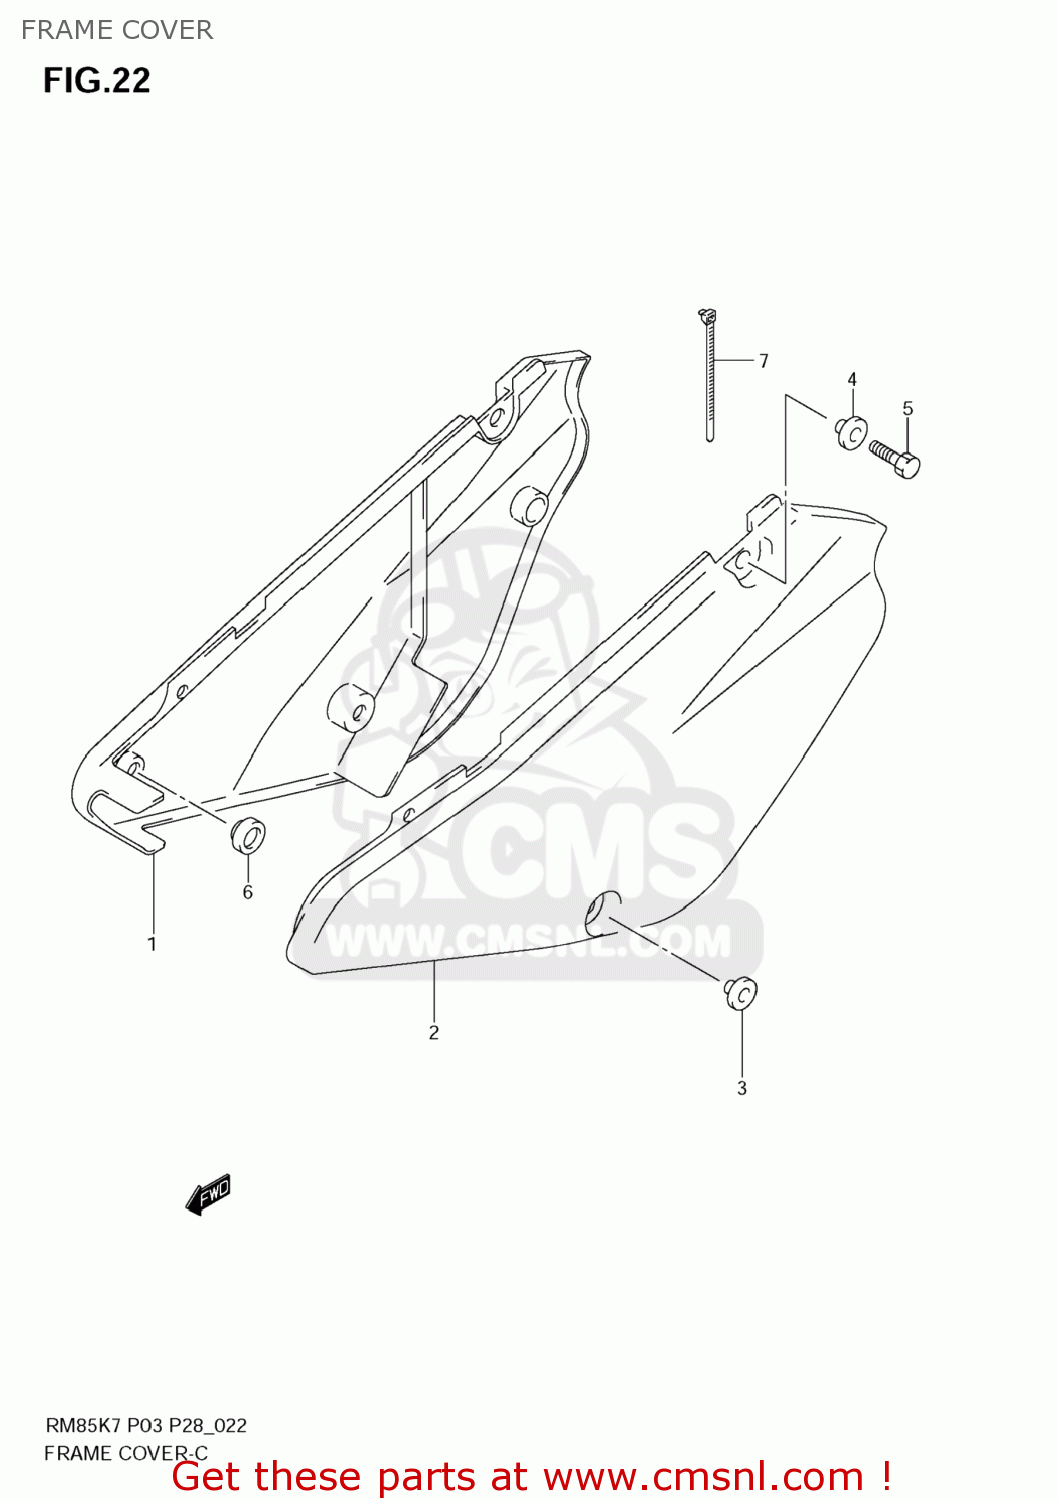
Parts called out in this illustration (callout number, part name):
1	COVER,SIDE,R(WHITE)
2	COVER,SIDE,L(WHITE)
3	WASHER
4	WASHER(6.5X20X1.6)
5	BOLT(6X16)
6	CUSHION
7	CLAMP(L:150)
